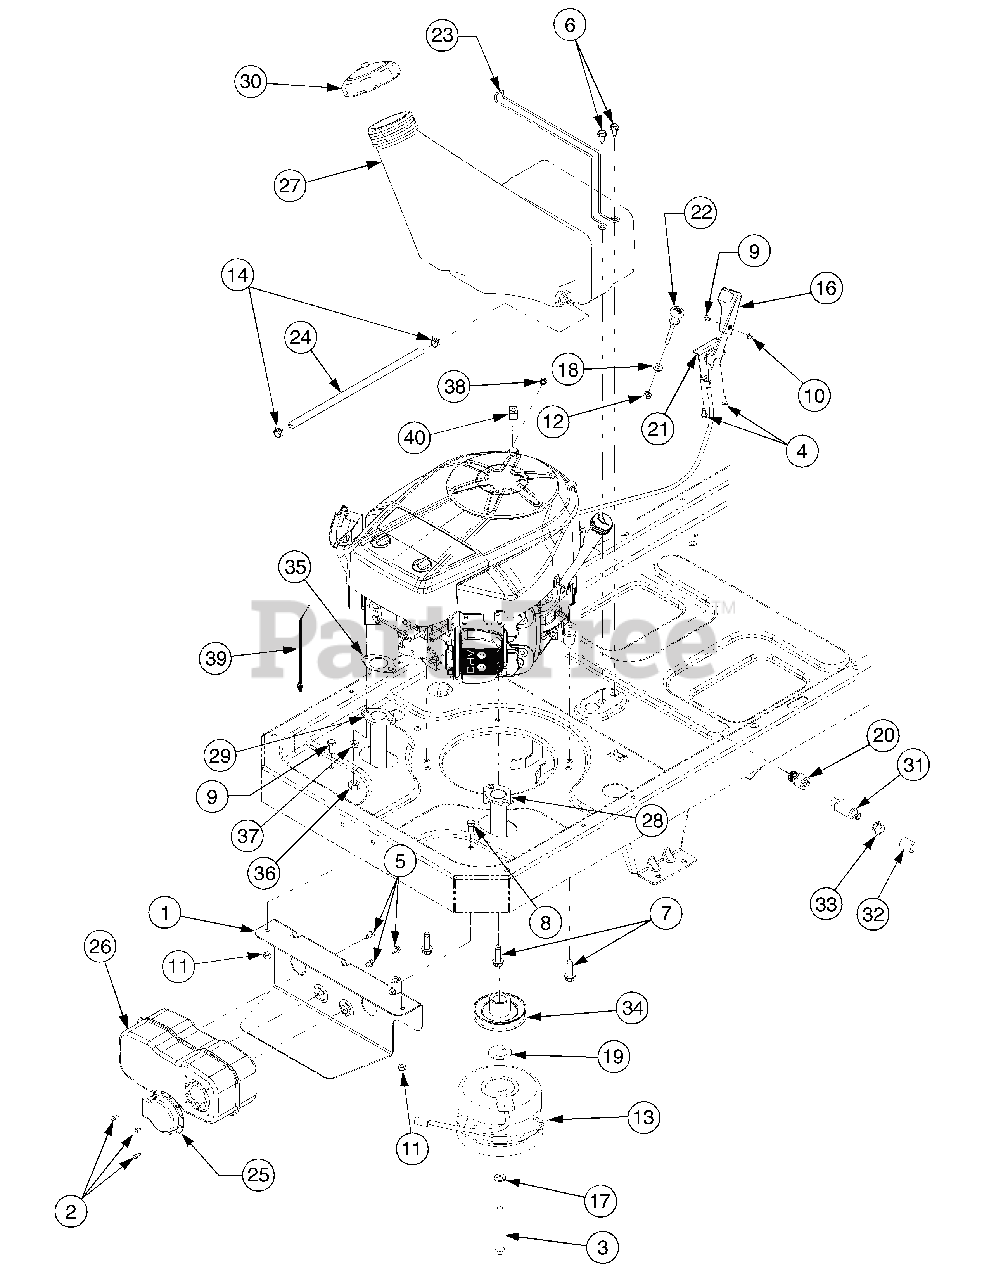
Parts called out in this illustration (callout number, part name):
1	Bracket, Muffler Mounting
2	Screw, Hex Wash. Hd. Tapp #8-18 x .5
3	Screw, Hx Cap Lk., 7/16-20 x 3.5 GR5
4	Screw, Hex Wash. Hd. Tapp #12-16 x .5
5	Screw, Hex Wash. Hd. Tapp 1/4-20 x .5
6	Screw, Hex Wash. Hd. Tapp 5/16-12 x .75
7	Screw, Hex Wash. Hd. Tapp 3/8-16 x 1.25
8	Screw, Hex Cap, 5/16-18 x .75 GR5
9	Screw, Truss Hd. Mach. #8-32 x .375
10	Nut, Hex, #8-32
11	Nut, Hex Insert Lock, 5/16-18 GR5
12	Nut, Hex Jam, 3/8-16 GR2
13	Clutch Assembly, Electric PTO
14	Clamp, Hose
16	Knob, Throttle Control
17	Washer, Lock, 7/16
18	Washer, Flat, .406 x .875 x .059
19	Washer, Flat, 1.031 x 1.62 x .095
20	Fitting, Hex
21	Cable, Throttle, 34.25 Lg
22	Cable, Choke, 61Lg
23	Wire, Tank Mounting
24	Hose, Fuel Line 22 IN
25	Deflector, Muffler
26	Muffler
27	Tank, Fuel, 3.0 Gal.
28	Pipe, Exhaust RH
29	Pipe, Exhaust LH
30	Cap, Fuel
31	Drain, Oil
32	Hose, Oil Drain Extension
33	Cap,.Oil Drain
34	Pulley, Drive
35	Gasket, Muffler
37	Washer, Lock
38	Nut, Sems, 1/4-20
39	Tie, Push Mount Cable
